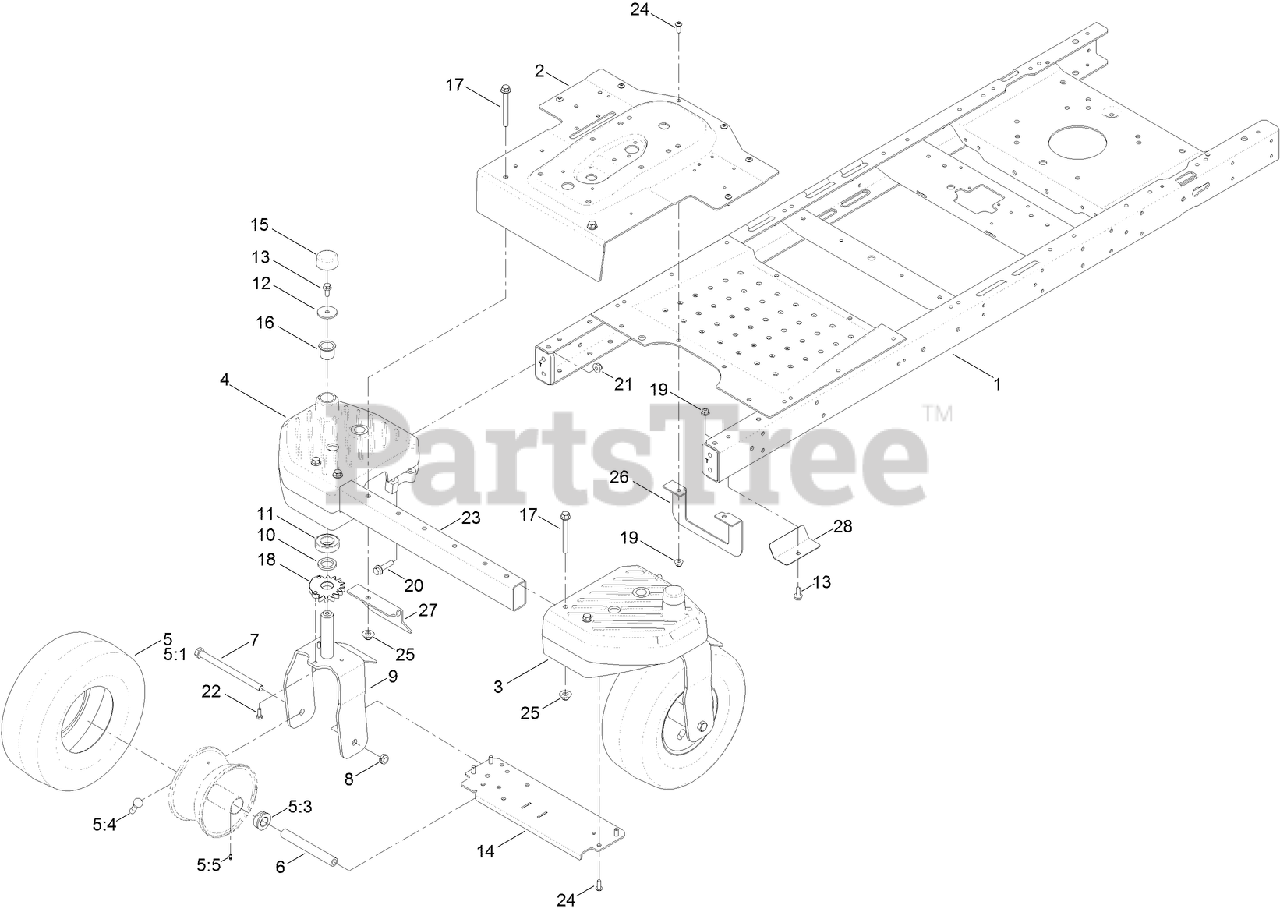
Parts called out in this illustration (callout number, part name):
1	FRAME ASM
2	PAN-STEER, FRONT
3	HOUSING-SPINDLE, LH
4	HOUSING-SPINDLE, RH
5	13 INCH WHEEL AND TIRE ASM
5:1	TIRE-13 INCH
5:3	BUSHING-FLANGE
5:5	FITTING-GREASE
6	SPANNER
7	SCREW-HH
8	NUT-HEX
9	CASTER FORK ASM
10	WASHER-THRUST
11	BEARING-BALL
12	WASHER-FLAT
13	SCREW-HHF
14	PLATE-BRIDGE, NARROW
15	CAP-CASTER
16	BUSHING-PIVOT
17	SCREW-HHF
18	GEAR-WHEEL, 15 TOOTH
19	NUT-HF, NI
20	SCREW-HHF
21	NUT-HF, NI
22	SCREW-HH
23	TUBE-FRONT, NARROW
24	SCREW-HSBH
25	NUT-FLANGE, NI
26	BRACKET-UPSTOP
27	GUARD-FRONT
28	PLATE-GUARD
